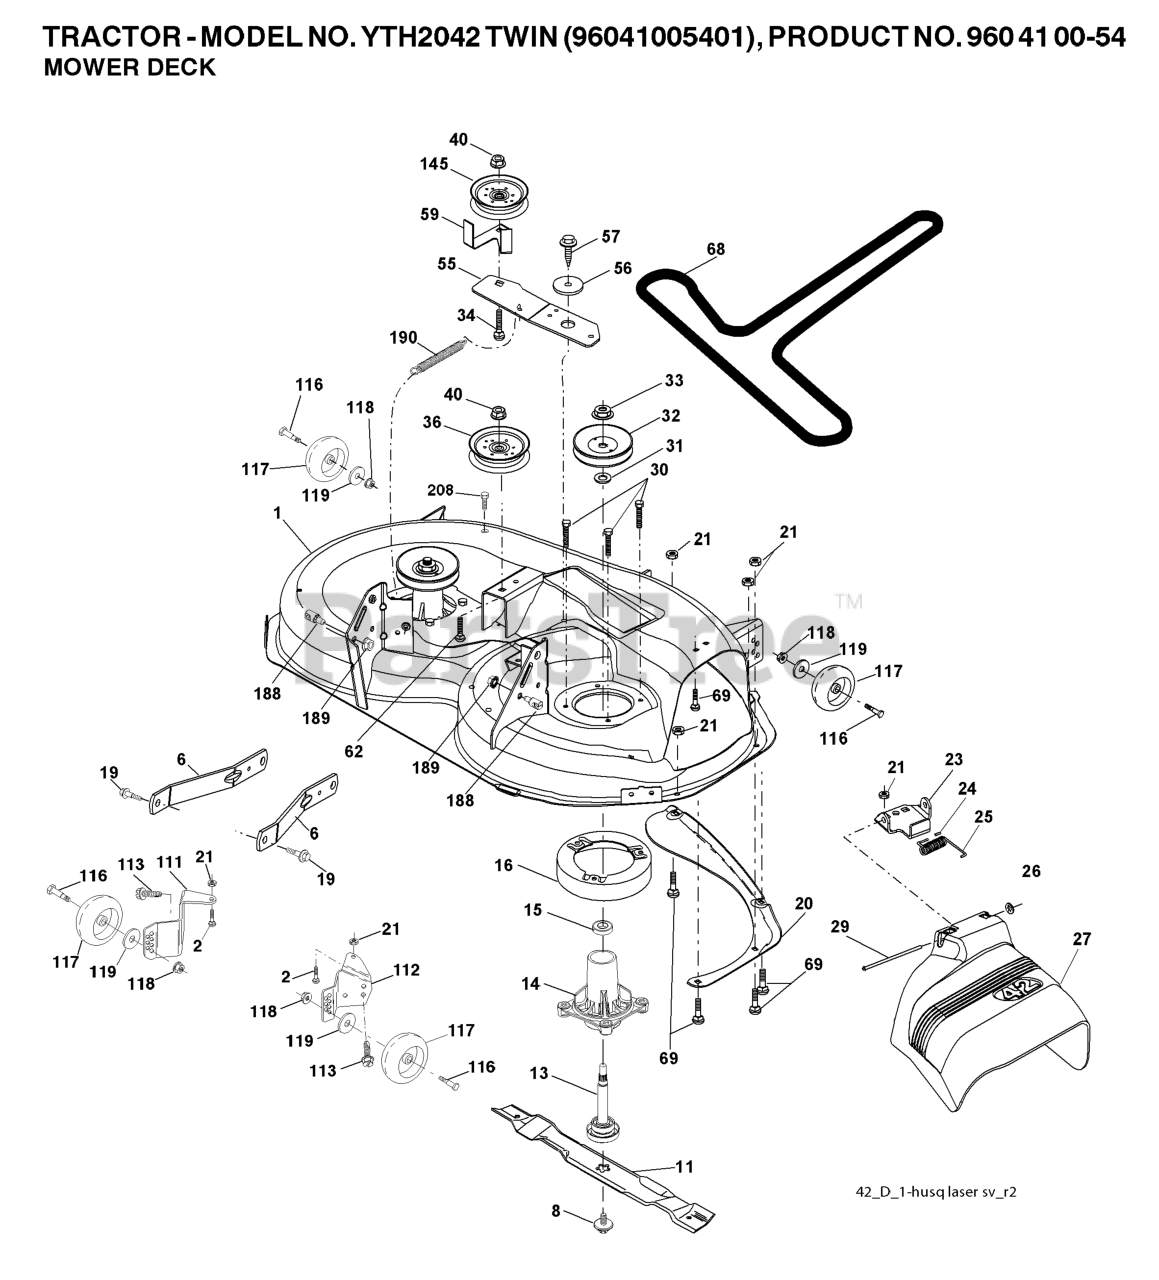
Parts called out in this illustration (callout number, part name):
1	DECK.WELDMENT.42"PAINT
2	RP BOLT 5/16-18 X3/4 ZN/YEL GR
6	ARM.SUSPENSION.MOWER.R
8	BOLT.WASHER.ASM.7/16-2
11	42" HI-LIFT BLADE
13	SHAFT.ASM.MDRL.N/GREASE.38
14	RP.HOUSING.MANDREL.4PT.
16	STRIPPER.MANDREL.ROUND.BLACK
19	BOLT.SHOULDER
20	BAFFLE.VORTEX
21	LOCKNUT
23	BRKT.DEFLECTOR.38"2005+
24	CAP-SLEEVE LT
25	SPRING.TORSION.DEFLECT
26	NUT PUSH M
27	SHIELD.DEFLECTOR.MOWER.42"BLAC
29	ROD.HINGE
30	SCREW, WASHER HEAD
31	WASHER.SPACER.MANDREL
32	PULLEY/MANDREL
33	NUT.FLANGE.LOCK.TOP
34	BOLT.3/8-16X1.50
36	PULLEY.IDLER.2006
40	NUT LOCK FLG 3/8-16 UNC
56	SPACER.RETAINER
57	SCREW 3/8-16X1
59	GUARD, BELT
68	BELT V SECONDARY
69	BOLT
111	BRKT.WHEEL.GAUGE.LH.42"
112	BRKT.WHEEL.GAUGE.RH.42"
113	BOLT.5/16HEX.WHS.HD
116	BOLT M
117	WHEEL.GAGE.HALF.SPOKED
118	LOCKNUT
119	WASHER.5/16.FLAT.STE.STD.
145	PULLEY.IDLER.48"PRIMARY
188	STUD.FASTNER.W/ANTI-ROTATE
189	NUT LOCK HEX FLANGE 5/16-18
190	SPRING.MOWER.DRIVE.ELECTRIC
208	SCREW 3/8-16X1/2
